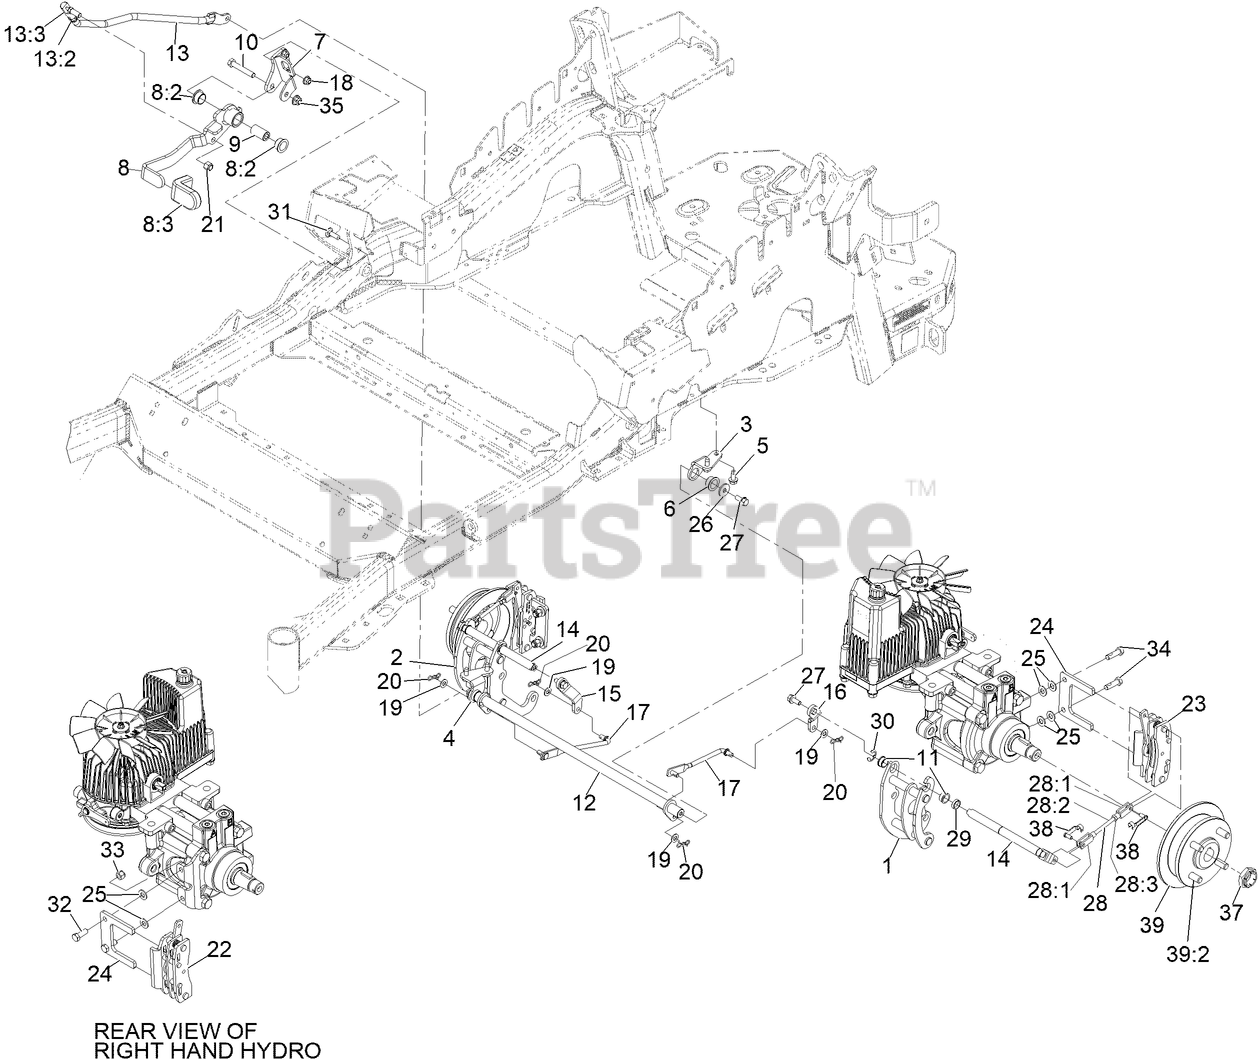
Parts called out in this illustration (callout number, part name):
1	MOUNT-BELLCRANK, LH
2	MOUNT-BELLCRANK, RH
3	MOUNT-PIVOT, LH
4	MOUNT-PIVOT, RH
5	SCREW-HWHTF
6	BUSHING-FLANGE
7	BRACKET-MOUNT
8	BRAKE LEVER ASM
8:2	BUSHING-FLANGE
8:3	GRIP-LEVER
9	HANDLE-PIVOT, BRAKE
10	SCREW-HH
11	BUSHING
12	SHAFT-CROSS
13	ASM, FRONT LINKAGE
13:2	END-TIE ROD, RH
13:3	NUT-HJ
14	BELLCRANK
15	ARM-INNER, RH
16	ARM-INNER, LH
17	MID-LINK, SHORT
18	NUT-HF, NI
19	WASHER-PLAIN
20	PIN-COTTER, LOCKING
21	NUT-LOCK
22	CALIPER-BRAKE, RH
23	CALIPER-BRAKE, LH
24	PLATE-MOUNT, BRAKE
25	WASHER-FLAT
26	WASHER-FLAT
27	SCREW-HHF
28	REAR LINKAGE ASM
28:2	LINKAGE, REAR
28:3	NUT-JAM
29	SPACER
30	E-RING
31	BOLT-CARR
32	SCREW-HH,
33	NUT-LOCK
34	SCREW-HH, PATCH,
35	NUT-HF, NI
37	LOCKNUT
38	PIN-CLEVIS, SPRING
39	WHEEL HUB ASM
39:2	STUD-WHEEL
